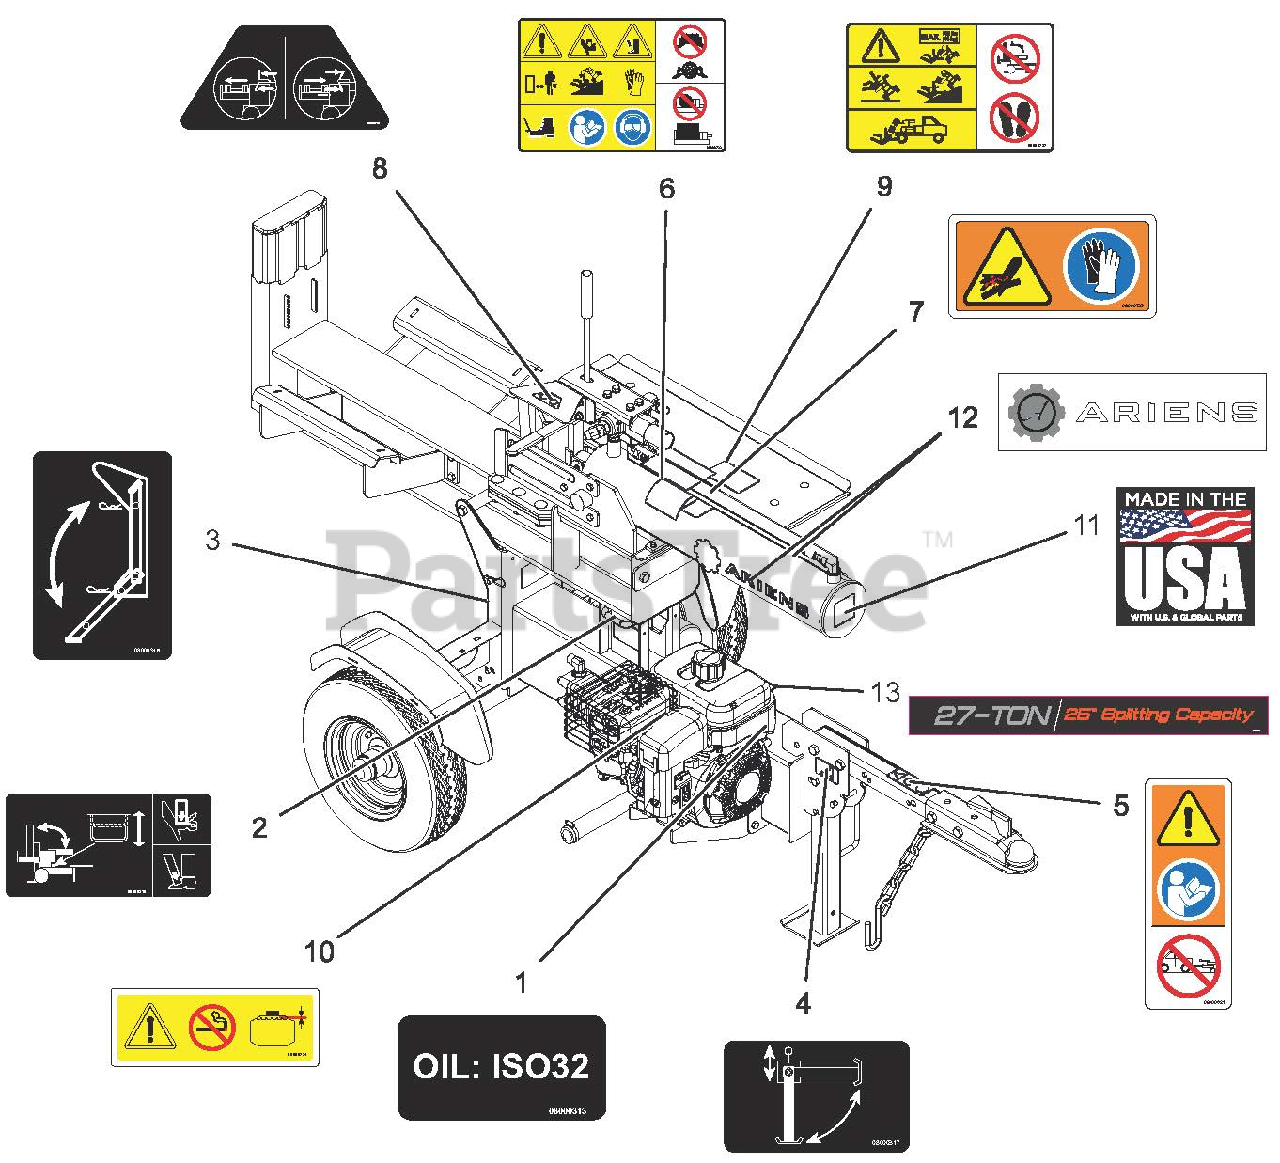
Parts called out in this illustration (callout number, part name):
1	DECAL, LOG SPLITTER-HYD OIL
2	DECAL, LOG SPLITTER-TILT OP
3	DECAL, LOG SPLITTER-REAR STAND
4	DECAL,LOG SPLITTER-FRONT STAND
5	DECAL, NO TOWING
6	DECAL,DANGER LOG SPLITTER
7	DECAL,HYD WARNING
8	DECAL,RAM OPERATION
9	DECAL,SPLITTER TABLE
10	DECAL,FUEL WARNING
11	DECAL, MADE IN USA
12	DECAL-ARIENS-CYLINDER
13	DECAL-CRADLE-27 TON
